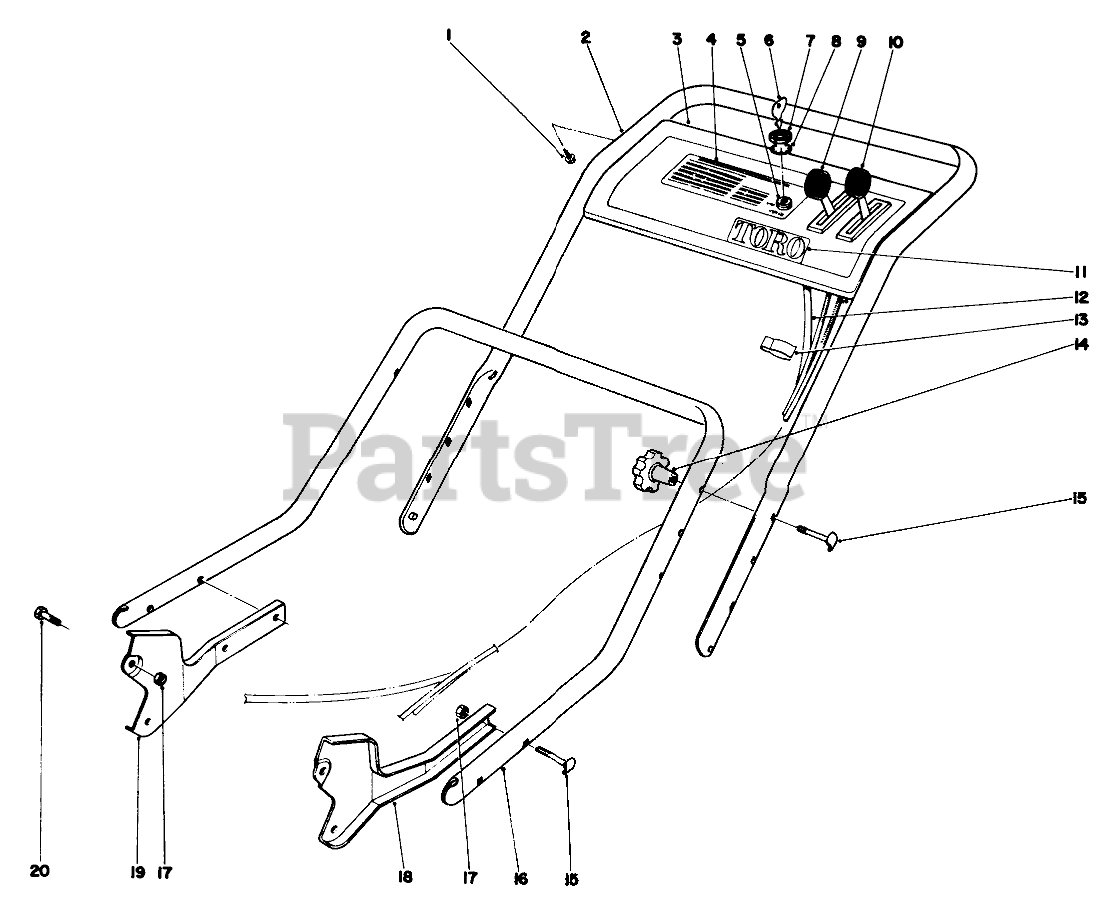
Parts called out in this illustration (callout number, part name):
1	SCREW-HWHTF
2	Upper Handle
3	Control Plate
4	Decal-Control Plate
5	Switch
6	Key
7	NUT-HH
8	WASHER-TOOTH, INTERNAL
9	SPEED CONTROL
10	Control Traction
11	Decal-Toro
12	Wire Harness
13	BOWDEN CLIP
15	HANDLE SCREW
16	Lower Handle
17	Nut
18	Latch Handle L.H.
19	Latch Handle R.H.
20	SCREW-HH
